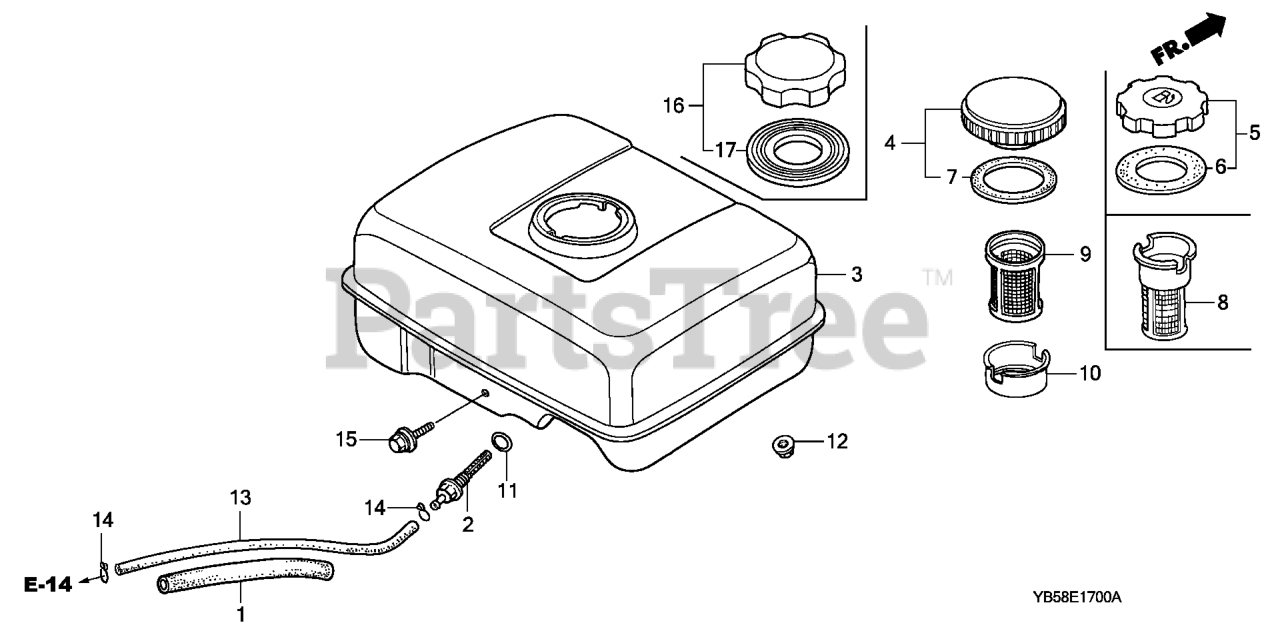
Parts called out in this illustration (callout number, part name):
1	RUBBER, SUPPORTER (107MM)
2	JOINT, FUEL TANK
3	TANK, FUEL *NH31* (MCKINLEY WHITE) Use up to Engine SN 3033315.
5	CAP, FUEL FILLER (BLACK) Use up to Engine SN 2115700.
5	CAP, FUEL FILLER (CHROME PLATED)
5	CAP COMP
6	GASKET, FUEL FILLER CAP (39X58X3) (NOT AVAILABLE)
6	GASKET, FUEL FILLER CAP Use from Engine SN 1543258.
6	GASKET, FUEL FILLER CAP (39X58X3)
8	FILTER, FUEL
11	O-RING (14MM) (ARAI) Use up to Engine SN 2949254.
12	NUT, FLANGE (6MM)
13	BULK HOSE, FUEL (4.5X3000) (Honda Code 5137104). (4.5X140)
14	CLIP, TUBE (B8)
15	BOLT, FLANGE (6X29)
16	CAP, FUEL FILLER (CHROME PLATED)
16	CAP COMP
17	GASKET, FUEL FILLER CAP (39X62X3) (TOUYOUSYA)
